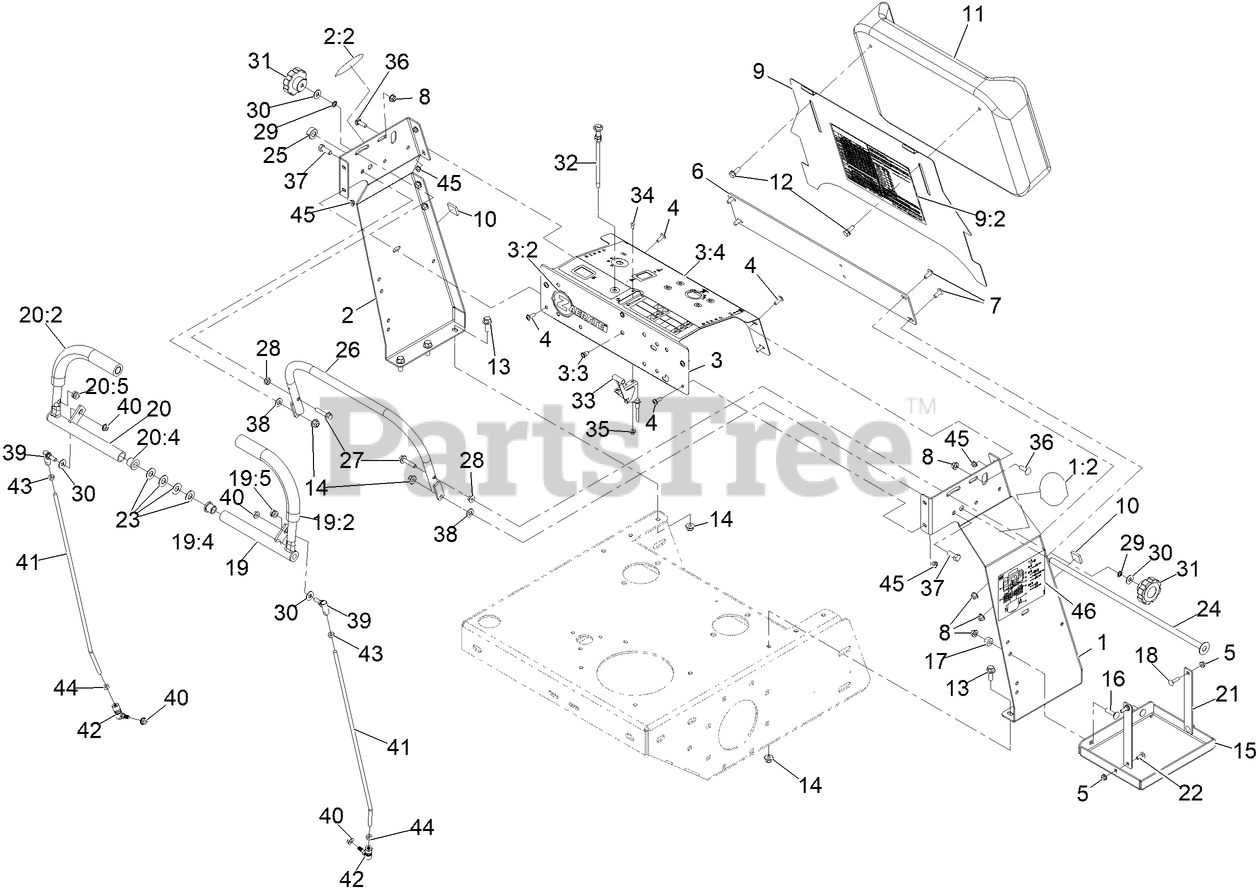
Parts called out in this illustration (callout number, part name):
1	PANEL-TOWER, LH
1:2	Decal-Z-Logo
2	PANEL-TOWER, RH
2:2	Decal-Z-Logo
3	PANEL-CONTROL
3:2	DECAL-Z-AERATE LOGO
3:3	Nut-Clinch, Hex
3:4	Decal-Control Panel
4	Screw-Hsbhf
6	PLATE-FACE
7	SCREW-PTH
8	NUT-HF, NI
9	PLATE-PAD,KNEE
9:2	Decal-Spray Chart
11	PAD-KNEE, Z-LOGO
12	SCREW-HHF
13	SCREW-HHF 3/8-16 X 1
14	NUT-HF, NI
15	TRAY-BATTERY
16	Bolt-Carriage 5/16-18 X 1 1/4
18	SCREW-CARR
19	HANDLE-CONTROL, LH ASM
19:2	GRIP-CONTROL, MOTION
19:4	Bushing,Flange,0.50 ID,0.75 OD
19:5	Grommet-Rubber
20	HANDLE-CONTROL, RH ASM
20:2	GRIP-CONTROL, MOTION
20:4	Bushing,Flange,0.50 ID,0.75 OD
20:5	Grommet-Rubber
21	Strap-Battery
22	BOLT-CARR
23	WASHER-PIVOT
24	Rod-Pivot, Joy Stick
26	Bar-Speed [red]
27	SCREW-HHF
28	Nut-Flange
29	Washer-Lock
30	FLAT WASHER, 5/16 NOM,ST
31	KNOB-FLUTED
32	CABLE-CHOKE
33	CABLE-THROTTLE
34	Screw-HSBH
35	Nut-Hex Flange
36	SCREW-CARR
37	SCREW-HH
38	WASHER-FLAT
39	Balljoint-SS
40	Nut-HHF
41	ROD-CONTROL
42	Ball Joint-Quick Disconnect, SS
43	Nut-Hex
44	Nut-Hex
45	Nut-Hex Flange
46	Decal-Service Aid
